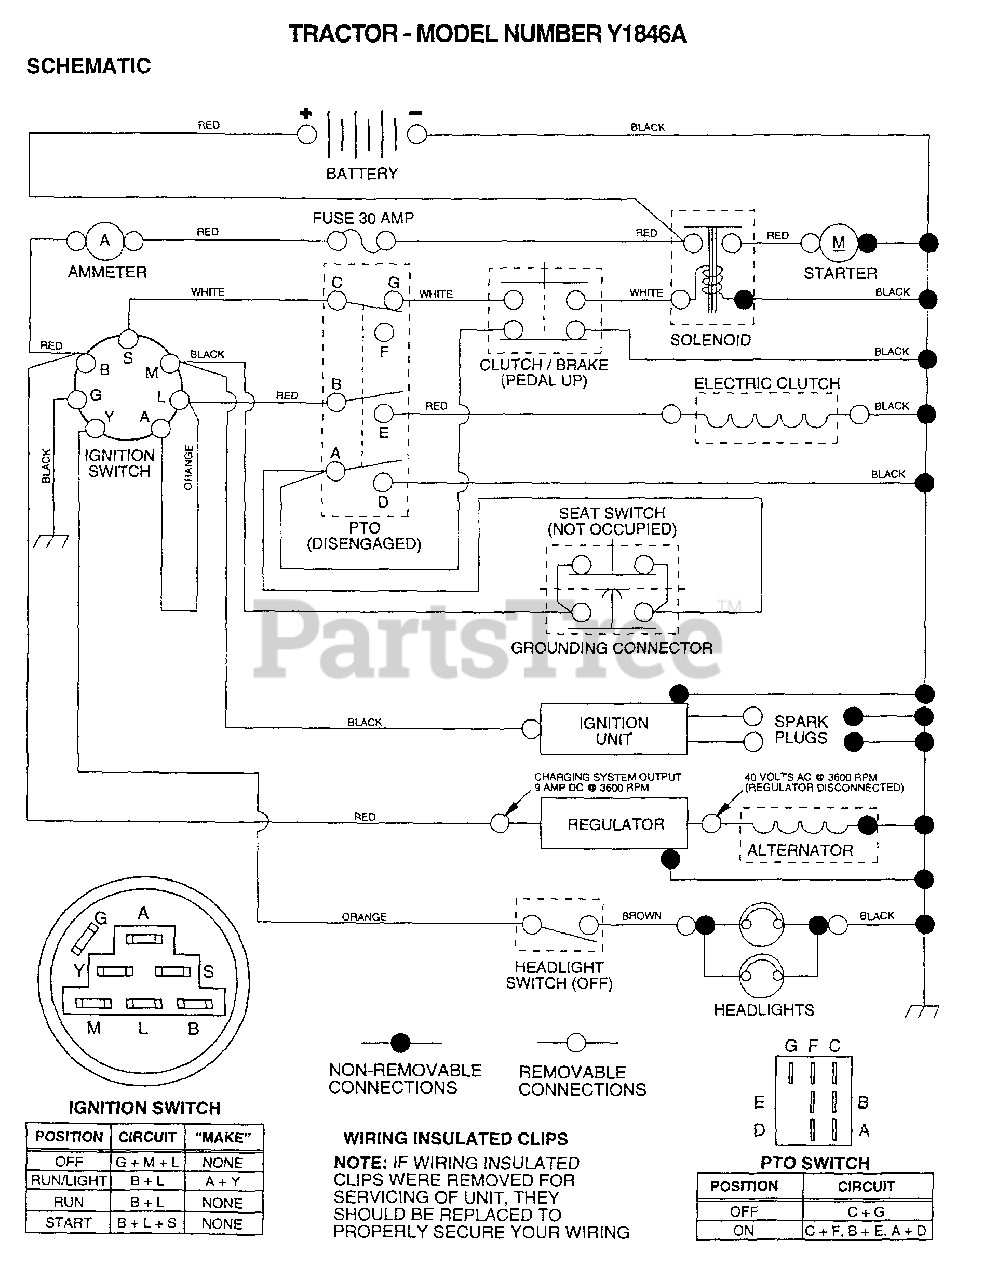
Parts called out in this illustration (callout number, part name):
1	NUT HXKEP 1/4X20
2	CABLE ASM.
4	LOCKNUT
5	BRACKET LT
6	SWITCH INTERLOCKT
7	KEEPER.ACTUAT.LR.
8	SCREW
9	KEY STEEL DELTA
10	COVER KEY SWITCH
15	SWITCH SEAT
17	FUSE HYT
18	CABLE ASSY
19	HARNESS.IGN.FEND.
20	NUT
22	BOLT HXHD FIN
26	BOLT LT
27	WASHER
28	LOCKWASHER
36	LOCKWASHER
39	BRACKET SWT CLUTC
55	SCREW LT
70	HARNESS ENG DUAL
